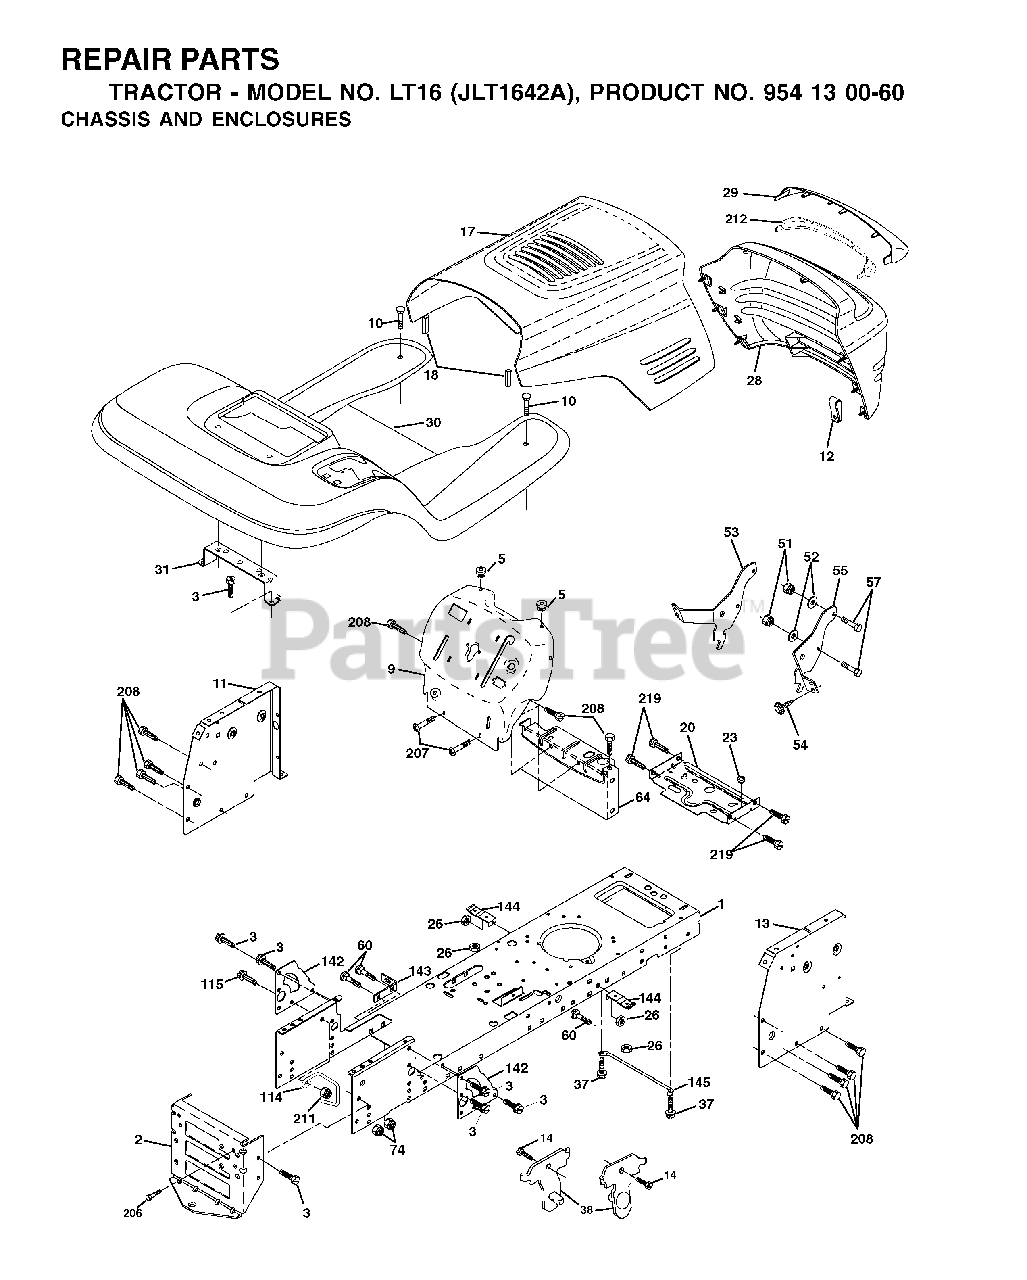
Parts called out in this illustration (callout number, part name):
1	CHASSIS STAMPING
2	DRAWBAR, 12GA
3	SCREW 3/8-16X3/4
5	BUMPER.RUBBER.HOOD
9	PANEL.DASH.LH.LTX
10	BOLT D
11	PANEL DASH LH
13	PANEL ASM, DASH RH
18	BUMPER HOOD T
20	PLATE MTG.BATTERY/FUEL TANK
23	GROMMET T
26	NUT
38	BRACKET.ASM.PIVOT.MOWER.REAR
51	LOCKNUT
57	BOLT
64	DASH LOWER
74	LOCKNUT
115	SCREW.3/8-16
142	PLATE REINFORCEMENT
143	BRACKET, SWAY BAR
144	BRKT, FOOT REST
145	ROD PIVOT CHASSIS/HOOD
206	SHOULDER BOLT 5/16-18TT
207	SCREW, 5/16-18 X 1/2
208	SCREW 3/8-16X1/2
211	NUT
219	SCREW
